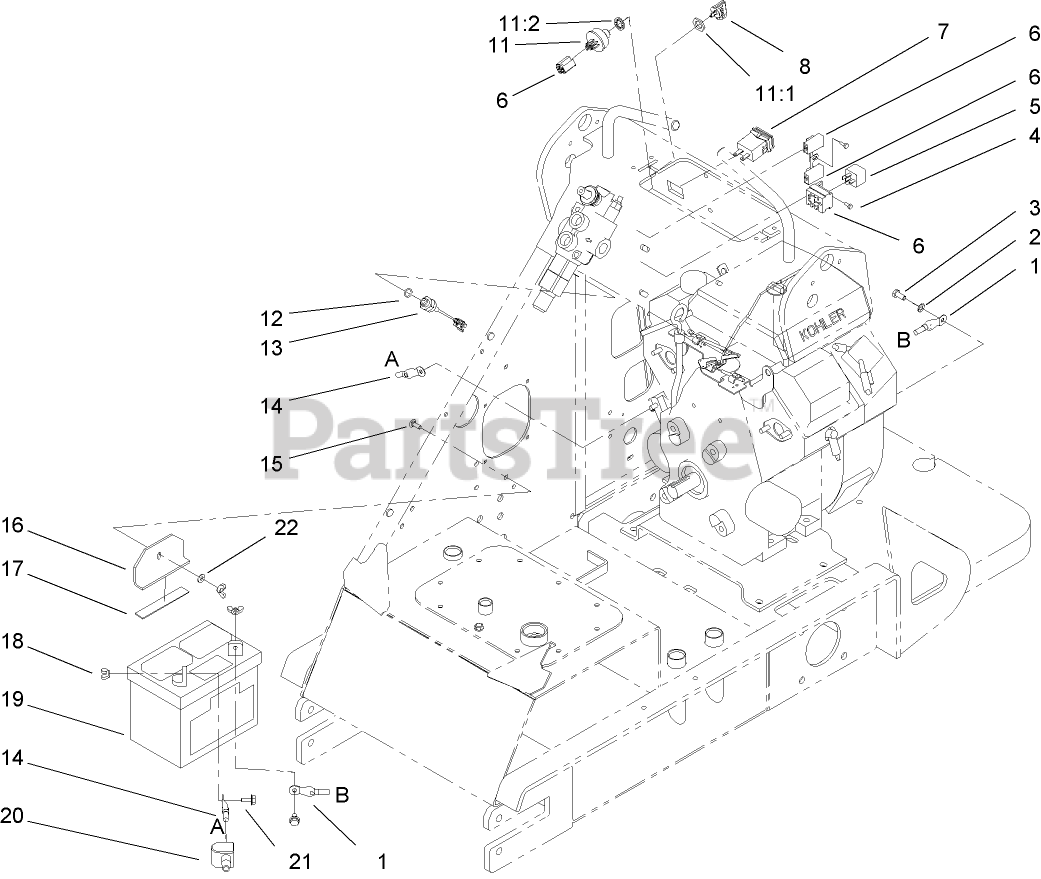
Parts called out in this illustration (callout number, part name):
1	CABLE-BLACK
2	WASHER-LOCK
3	SCREW-HH
4	SCREW-HWHTF
5	RELAY
6	HARNESS-ELECTRICAL
7	HOURMETER
8	KEY-IGNITION
11	KEY SWITCH ASM
11:2	WASHER-LOCK
12	O-RING
13	SWITCH-BALL
14	WIRE-21 INCH
15	SCREW-CARR
16	CLAMP-BATTERY
17	PAD-FOOTREST
18	NUT-WING
19	BATTERY-DRY
20	BOOT-TERMINAL, RED
21	SCREW-HHF
22	WASHER-FLAT
